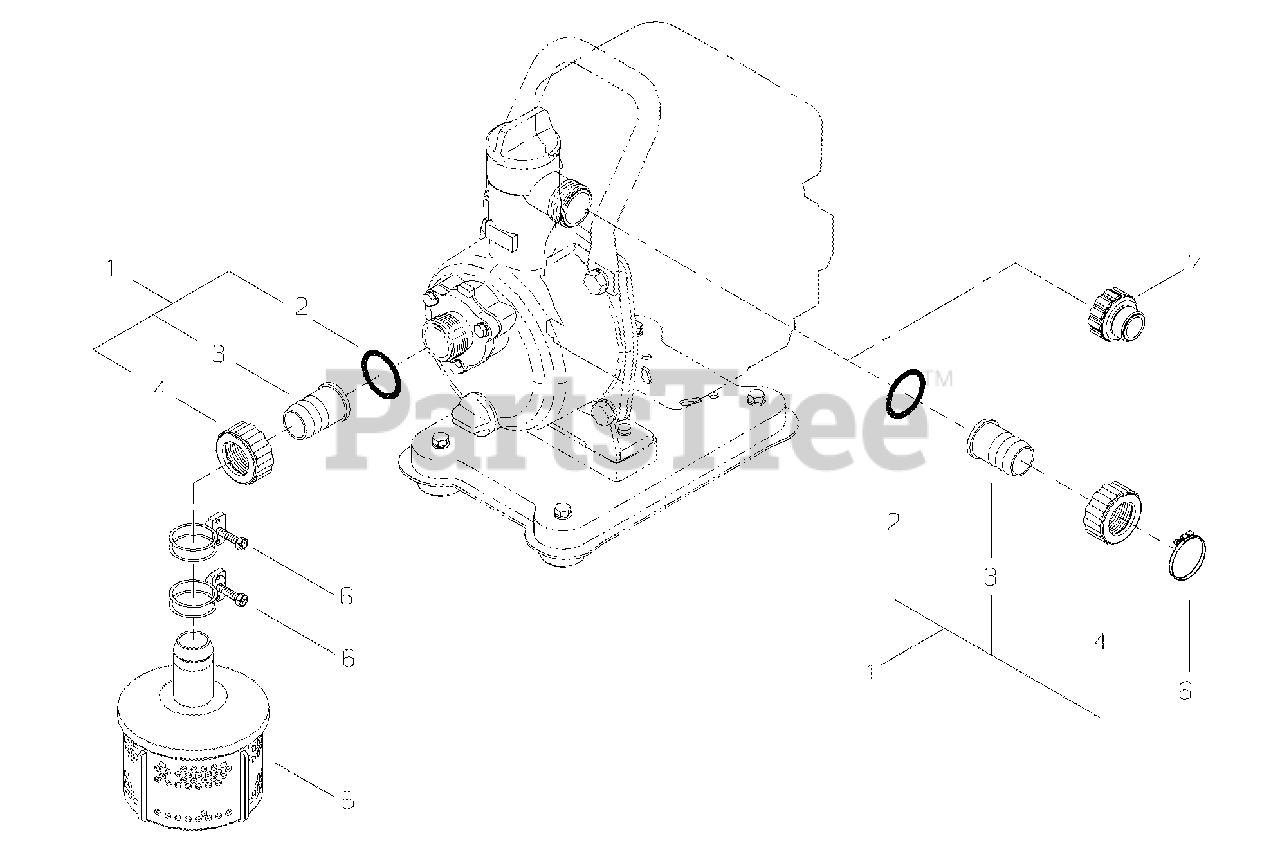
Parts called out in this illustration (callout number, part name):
1	HOSE COUPLING KIT
2	WASHER
3	COUPLING, HOSE
4	RINGNUT
5	STRAINER, DEBRIS
6	CLAMP, HOSE
7	ADAPTER, HOSE
